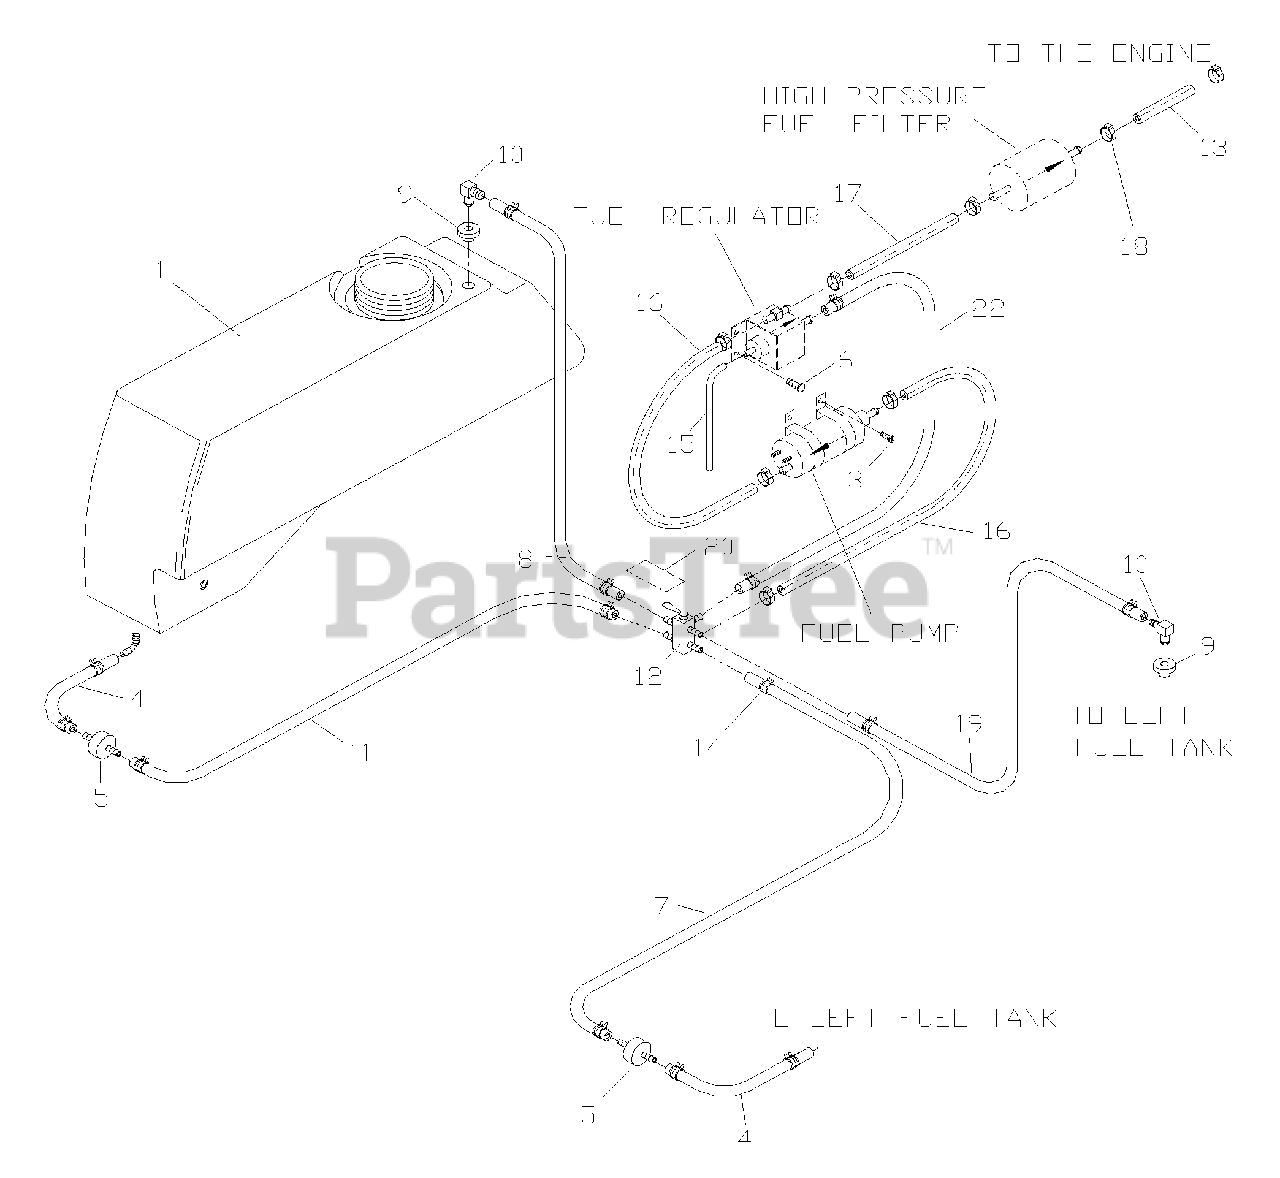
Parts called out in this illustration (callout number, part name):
1	RT. FUEL TANK
3	SELF TAPPING SCREW
6	1/4-20 SELF TAPPING SCREW
7	FUEL LINE
8	FUEL LINE
9	RUBBER GROMMET
11	FUEL LINE
12	FUEL VALVE
13	HOSE, FUEL INJ .31 ID X 30"
14	HOSE CLAMP
16	HOSE, FUEL INJ .31 ID X 27"
17	HOSE, FUEL INJ .31 ID X 18"
20	DECAL, FUEL VALVE
22	HOSE, FUEL .25 ID X 30"
